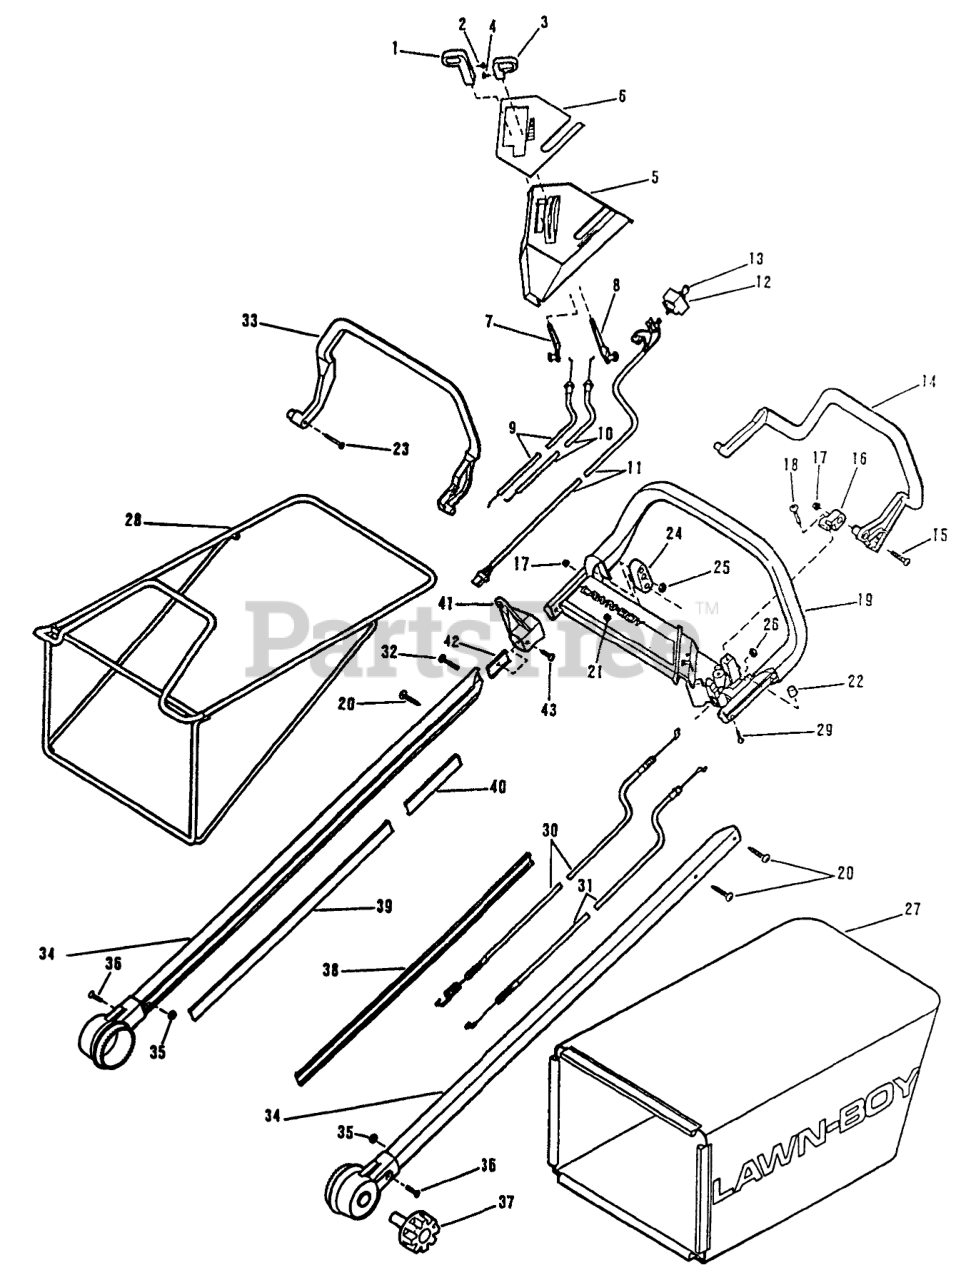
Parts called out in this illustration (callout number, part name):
1	KNOB & SCREW AY
2	SCREW-SELF TAP
3	KNOB & SCREW AY
4	SCREW-SELF TAP
5	UPPER CVR&DECAL AY
6	DECAL-LOGO-INSTR
7	LEVER ASSM SPD SEL LB
8	LVR ASSM THROTTLE LB
9	CABLE AY. WESCON
10	CABLE
11	WIRE HARNESS
12	Key Switch
13	KEY
14	BAIL-S.P.
15	SCREW - TRUSS HEAD
16	PIVOT BAIL PL
17	LOCKNUT FLAN
18	SCREW - TRUSS HEAD
19	Handle and Decal Assembly
20	SCREW
21	DECAL - LAWNBOY
22	BUMPER
23	SCREW - TRUSS HEAD
24	BLOCK BAIL PL
25	LOCKNUT E
26	NUT - HEX JAM
27	REPL BAG FOR 684190
28	FRAME AY-GRASS BAGB
29	SCREW - TRUSS HEAD
30	Cable Assy-Self-propelled
31	CABLE ASSEMBLY
32	SCREW-TRUSS
33	Blade Brake Bail
34	Handle Shaft Assembly
35	LOCKNUT FLAN
36	SCREW
37	KNOB-HDLE MT.ASMB
38	Handle Insert-Cable Side
39	INSERT-HANDLE
40	INSERT - HANDLE
41	ROPE GUIDE AY
42	NUT LB
43	SCREW
